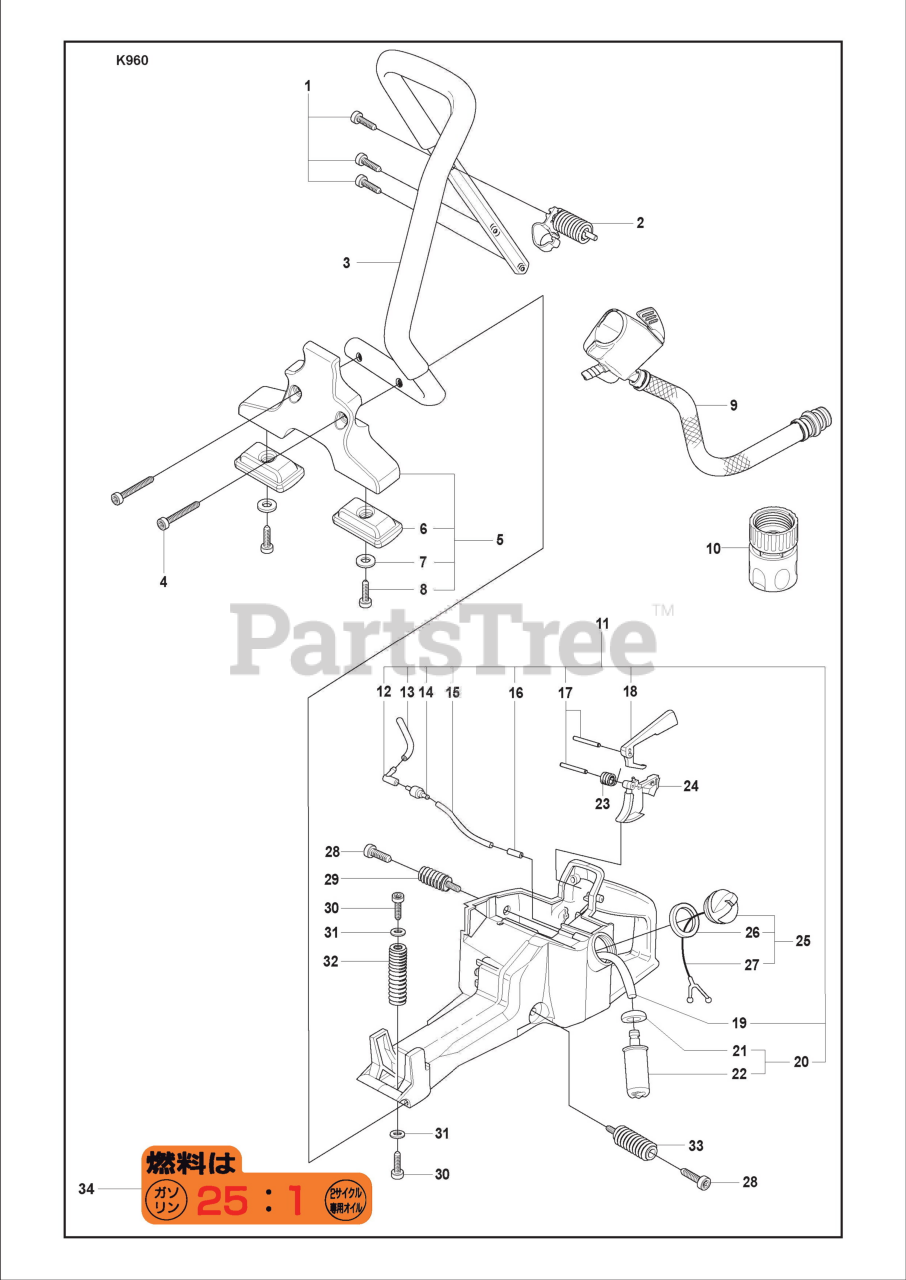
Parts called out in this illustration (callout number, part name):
1	Antivibration Element
5	Ground Support Assy
6	Base Ground Support
9	Hose
10	Coupler
11	Fuel Tank
12	Connection Bend
13	Fuel Hose
15	Fuel Hose
17	Parallel Pin
18	Throttle Lockout
19	Fuel Hose
20	Fuel Filter
21	Hose Clamp
22	Fuel Filter
23	Spring Throttle Trig
24	Throttle Trigger
25	Tank Cap Assy
27	Tank Cap Holder
29	Antivib Element
31	Washer Steel
32	Antivib Element
